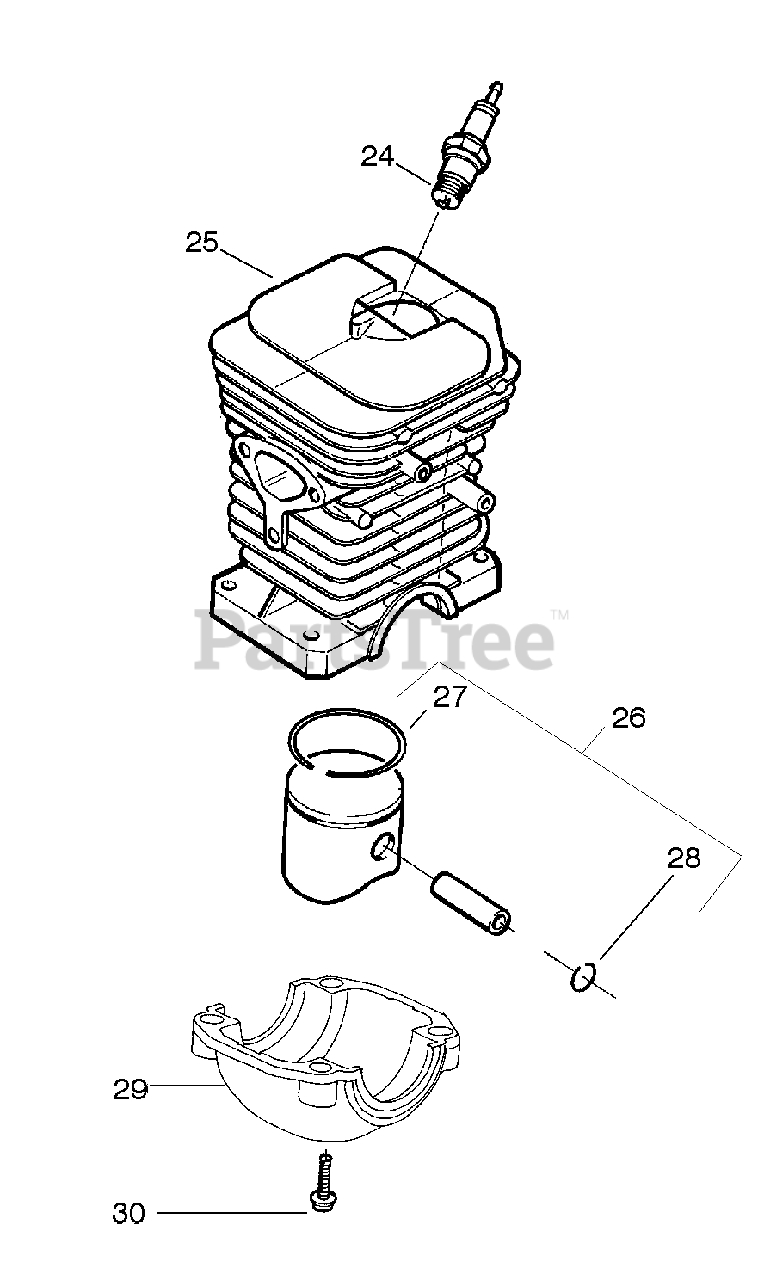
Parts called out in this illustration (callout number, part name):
24	Spark Plug
25	Kit-Cylinder
26	Kit-Piston
27	Ring-Piston
28	Piston Pin Retainer
29	Cap-Crankcase
